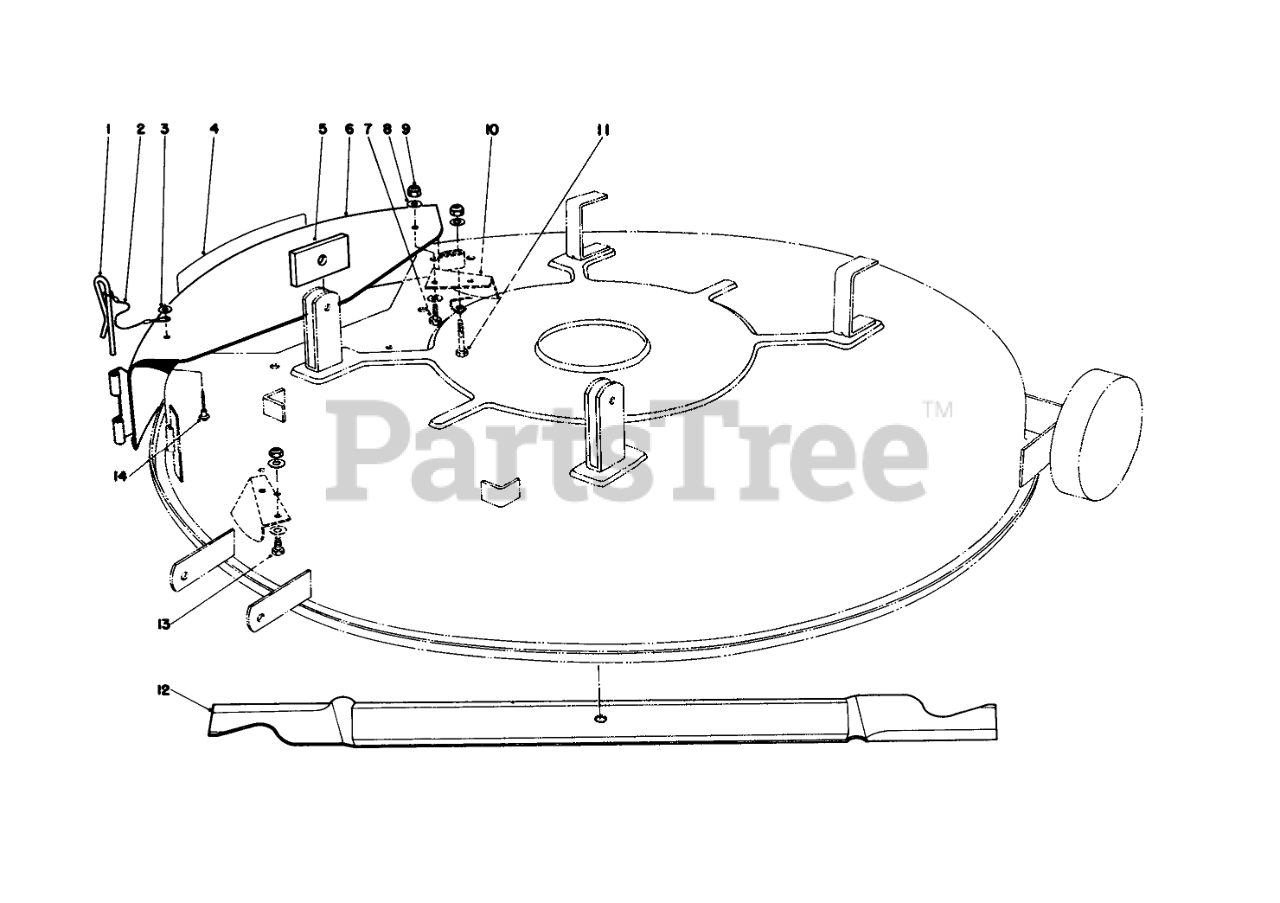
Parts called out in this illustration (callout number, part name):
1	PIN-LOCKING, CHUTE
2	LANYARD
3	WASHER-PLAIN
4	COVER DECAL
5	SPACER
6	Cover-Mulcher Assembly (Incl. Ref. #1-4 & 14)
7	SCREW-HH
8	WASHER-PLAIN
9	NUT-LOCK, NI
10	KICKER B
11	SCREW-HH
12	Blade
13	SCREW-HH
14	Rivet-Pop
